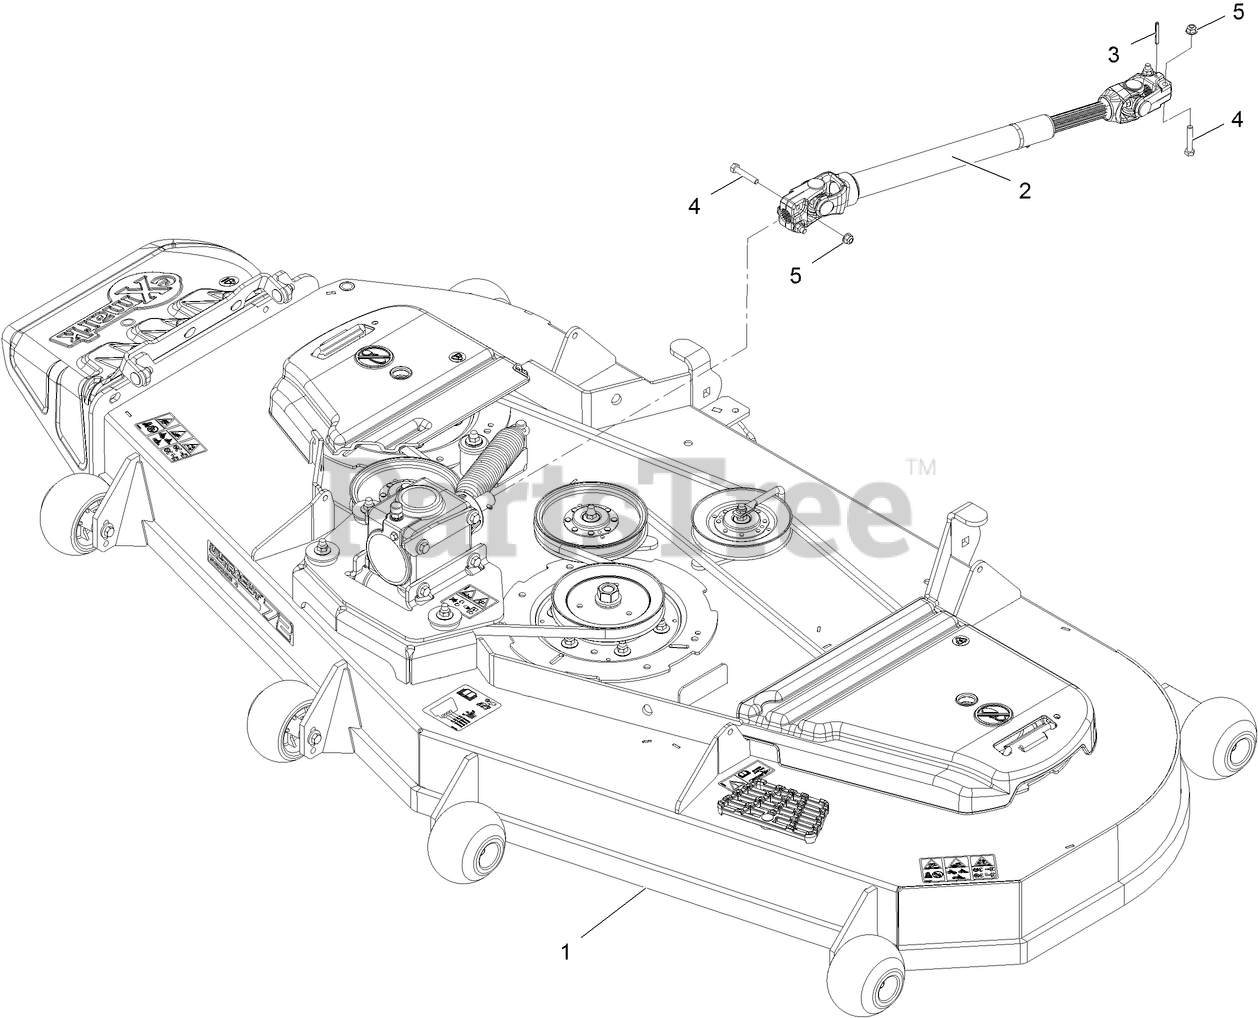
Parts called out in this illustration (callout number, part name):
1	Deck ASM-724
2	DRIVESHAFT ASM
3	PIN-ROLL
4	SCREW-HH
5	NUT-HF, NI
